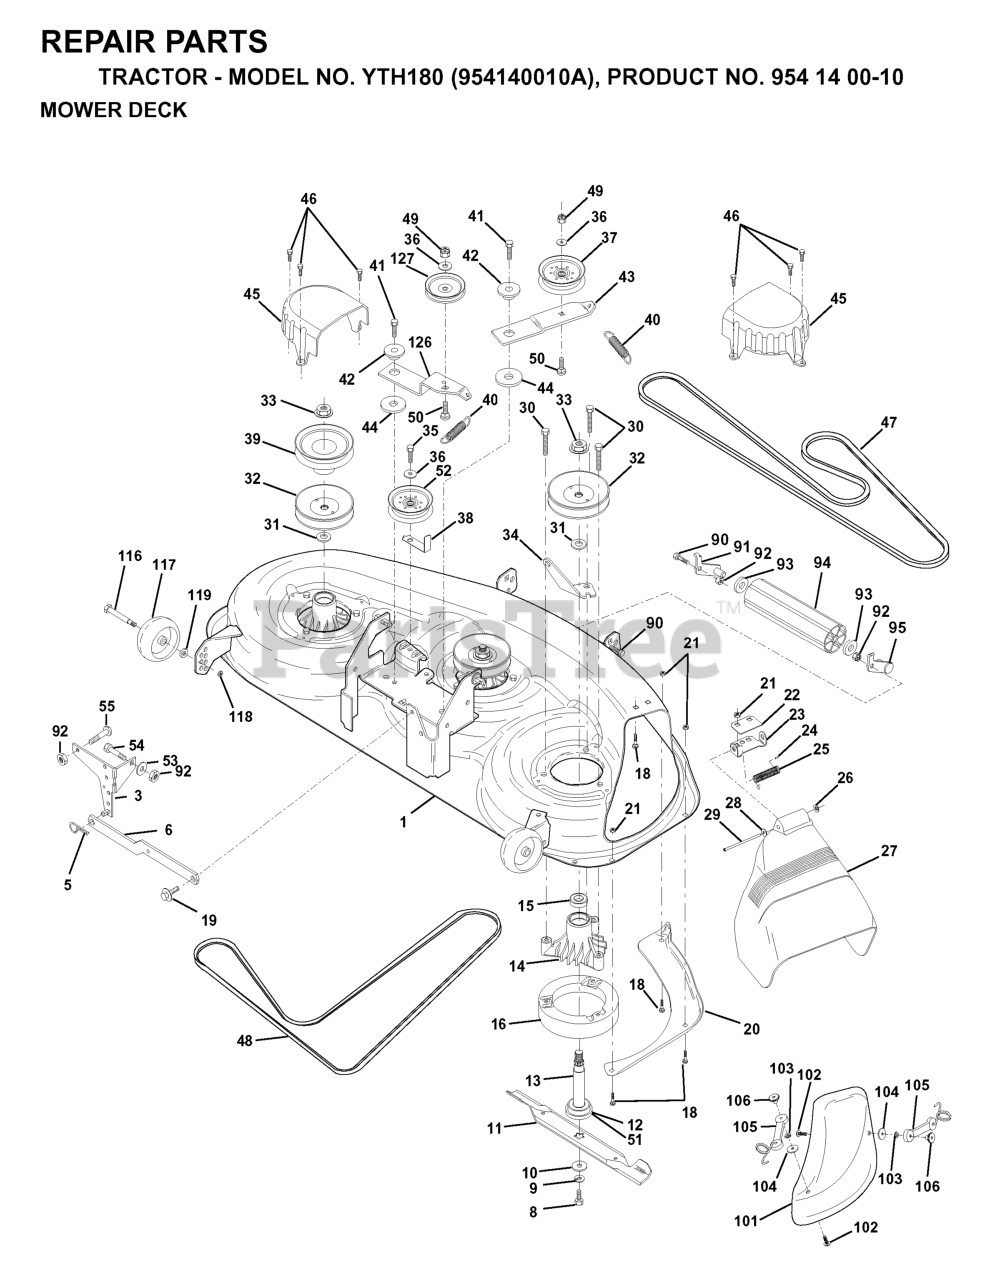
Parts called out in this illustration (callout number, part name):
1	HOUSING MOWER
3	BRACKET SWAY BAR
5	RETAINER-SPRNG RB
6	REAR SUSP ARM
8	BLADE BOLT
9	LOCKWASHER
10	WASHER.BLADE
11	MULCH BLADE 46"
12	BEARING.BALL.#6204.(MANDREL)
13	SHAFT.ASM.W/BEARING
14	HOUSING.MANDREL.44/46" VENT
16	STRIPPER
18	BOLT
19	BOLT SHD 5/16-18
20	BAFFLE, VORTEX MOWER 46"
21	LOCKNUT
22	STIFFENER BRACKET
23	DEFLECTOR BRACKET
24	CAP-SLEEVE LT
25	SPRING TORSION
26	NUT PUSH M
27	SHIELD, DEFLECTOR MOWER
28	Washer 11/32 x 5/8 x 16 Ga SD
29	ROD.HINGE
30	SCREW
31	WASHER
32	PULLEY, MANDREL
33	NUT
34	ANCHOR, SPRING DECK 46"
35	SCREW LT
36	WASHER
37	FLAT IDLER PULLEY
38	KEEPER
39	PULLEY.DRIVEN.DECK.46"
40	SPRING.SEC.44"VEN
41	SCREW
42	SPACER RETAINER
43	ARM IDLER DECK 46"
44	HARDENED WASHER
45	COVER MANDREL 46
46	SCREW.1/4-20X5/8
47	BELT V SECONDARY
48	V-BELT PRIMARY 50"
50	BOLT.3/8-16X1.50
51	WASHER FELT
52	PULLEY IDLER FLAT 46 PRI DRIVE
53	WASHER
55	BOLT D
90	BOLT
91	BRACKET LH (A)
92	NUT
93	Washer 1 17/32 X 7/8 X 16 Ga
94	NOSE ROLLER
95	BRACKET RH (B)
101	COVER.MULCH.46"3-BLADE.(2 2)
102	SCREW
103	LOCKWASHER #10
105	LATCH ASSEMBLY
106	WELDNUT
116	BOLT, SHOULDER
117	WHEEL GAGE DONUT
118	LOCKNUT
119	WASHER.5/16.FLAT.STE.STD.
126	ARM IDLER PRIM 46
127	PULLEY.IDLER.4.25
